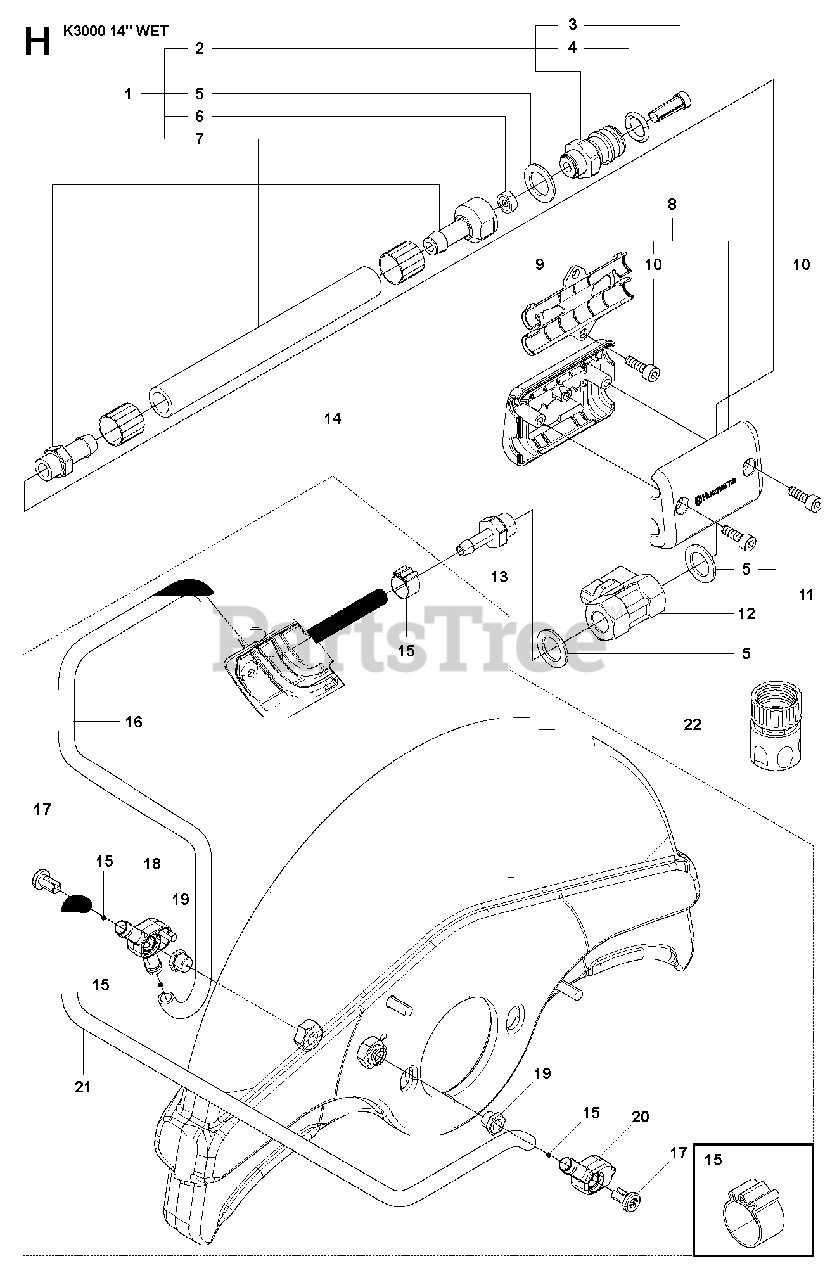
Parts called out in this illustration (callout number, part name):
1	HOSE ASSYIncl. 2, 5 - 7
2	NIPPLEIncl. 3, 4
7	HOSE KIT
8	HOUSINGIncl. 9 - 10
11	VALVE KITIncl. 5, 12
14	HOSE KITIncl. 15 - 21
16	HOSE720 mm
17	SCREW ITXSCM
